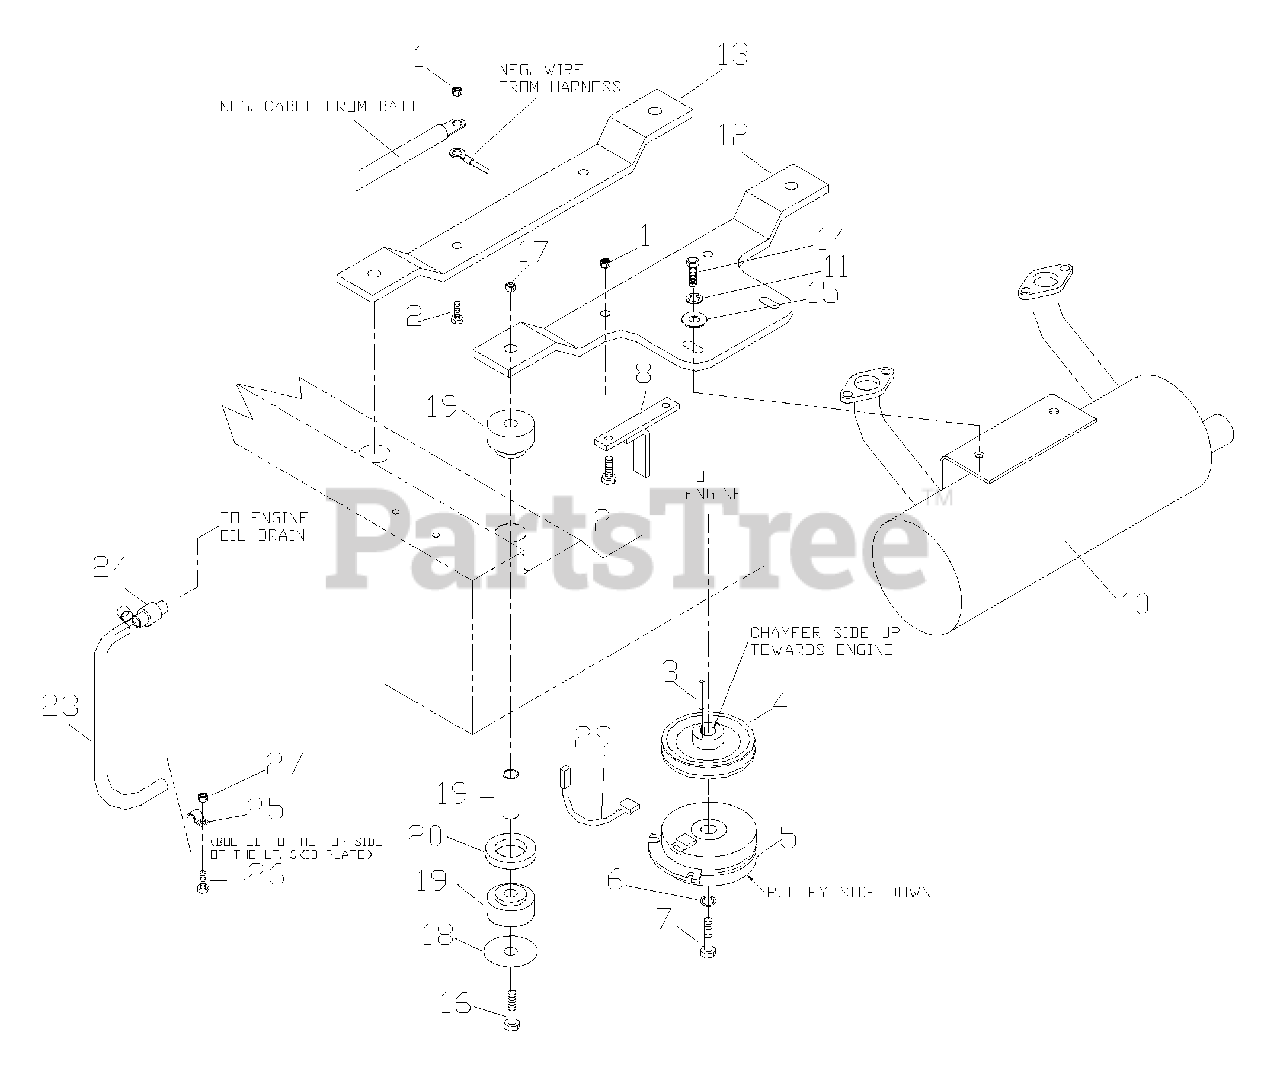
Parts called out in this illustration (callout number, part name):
1	NUT 5/16 LOCK
2	HCS 5/16 X 1.75
3	KEY 1/4 SQ
6	WASHER 7/16 LOCK
7	HCS 7/16F X 2.5
8	CLUTCH TIE DOWN
9	KOHLER PIGTAIL
11	WASHER 5/16 LOCK
12	ENGINE MOUNT
13	ENGINE MOUNT
14	HCS 5/16 X 750
15	WASHER 5/16 FLAT
16	HCS 1/2 X 3.25
17	NUT 1/2 NYLOC
23	OIL DRAIN HOSE
24	OIL DRAIN FITTING
26	HCS 1/4 X 750
27	NUT 1/4 CTR LOCK
29	CLUTCH PIGTAIL
